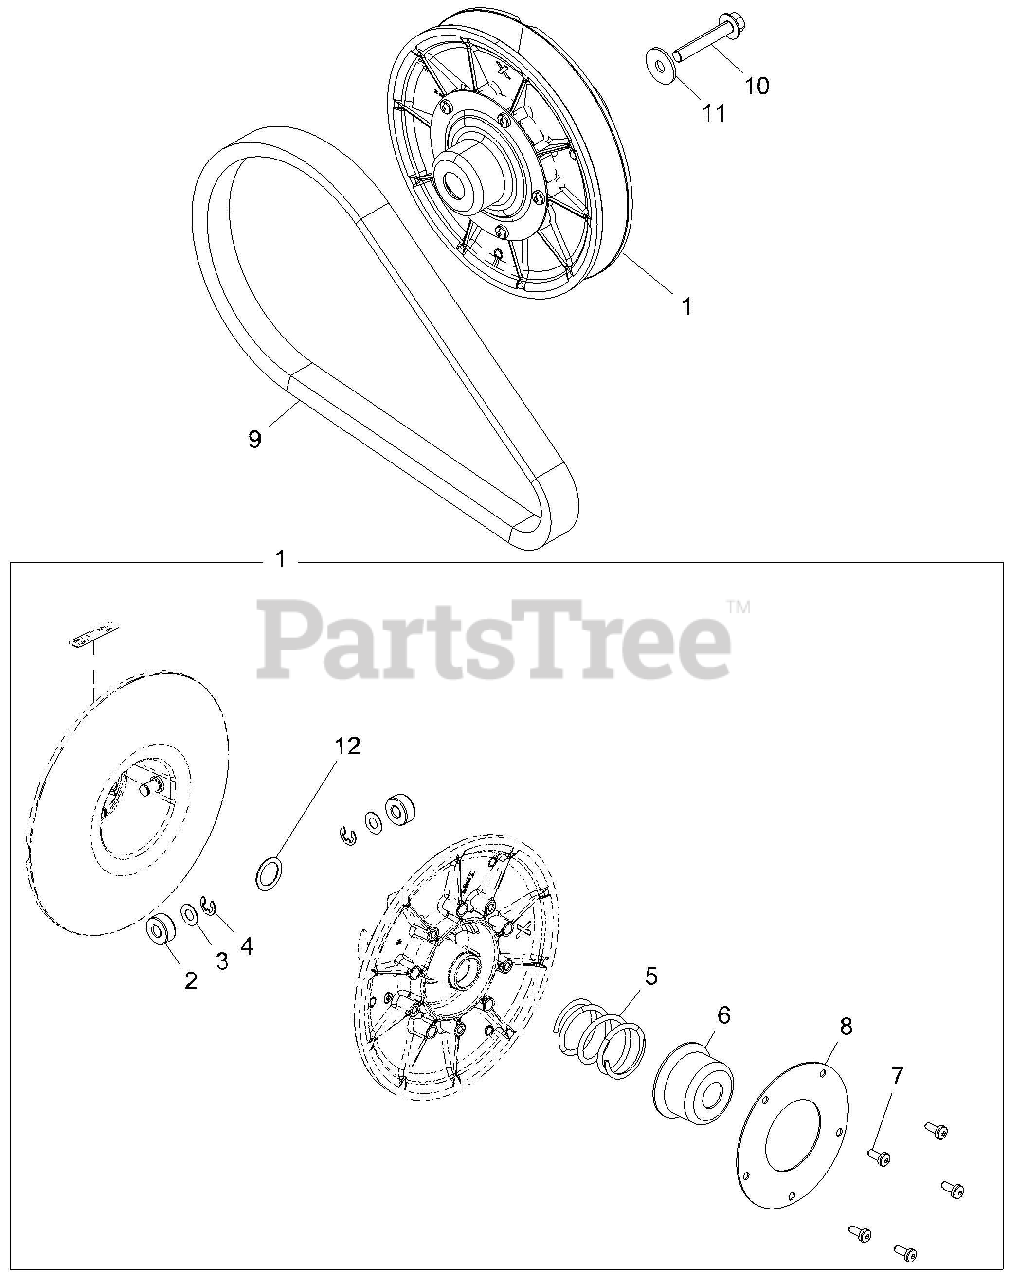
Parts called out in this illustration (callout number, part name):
1	ASM-CLUTCH,DRIVEN
2	ROLLER-CLUTCH,.955 ODX.450
3	WASHER-THRUST
4	RET.E-RING-E T.375
5	SPRING-COMPRESSION,RED/WHT
6	CUP-SPRING,BOSS LW UTILITY
7	SCR-TORX,M6X1.0X16
8	#N/A
9	BELT-DRIVE,11"CD
10	BOLT-M10X1.25X60,HXFLG-OLIVE D
11	WASHER, FLAT
12	WSHR-THRUST,1.189X0.838X0.12
